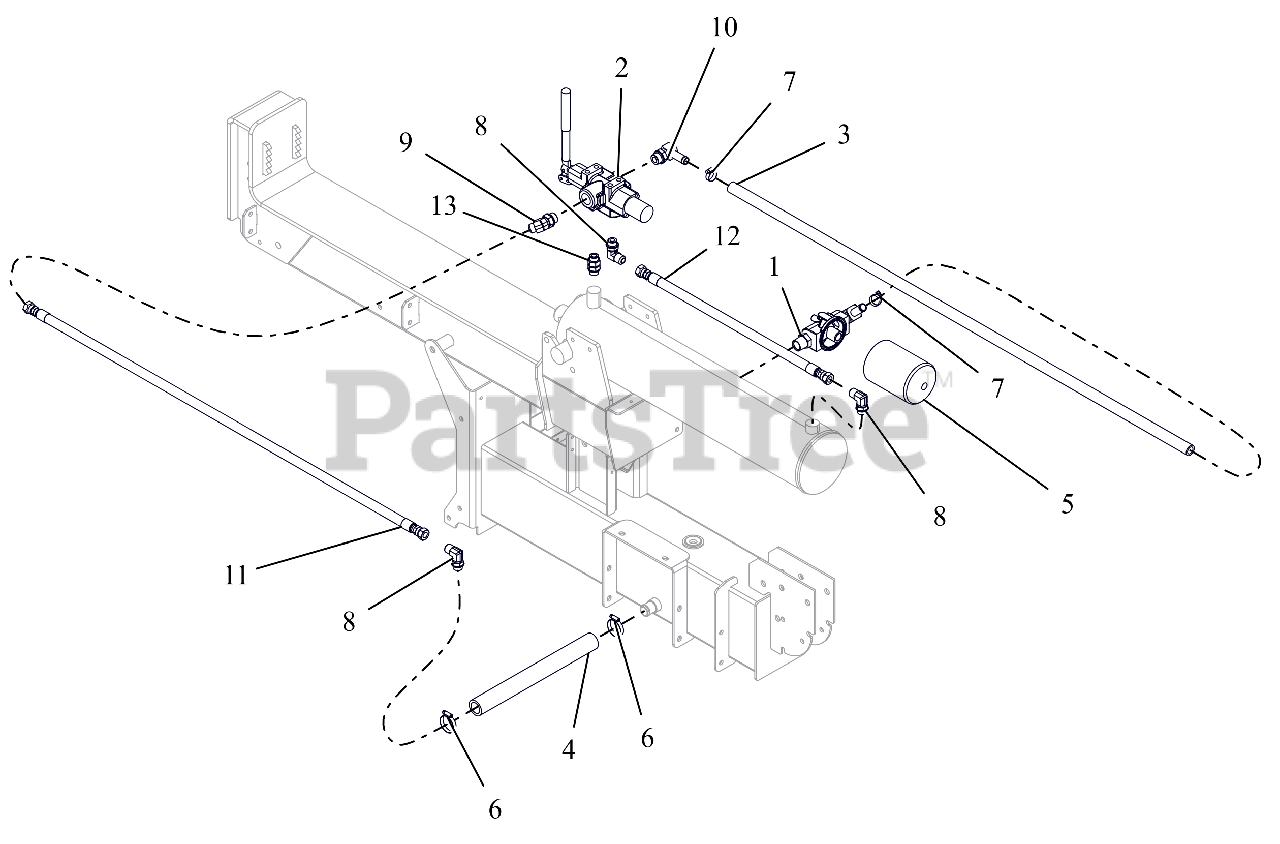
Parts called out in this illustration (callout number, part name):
1	ASM, FILTER HEAD
2	VALVE CONTROL-SPLITTER
3	HOSE,HYD RETURN 10LOLA X 53"
4	HOSE,HYD SUCTION 16G4H X 13.5
5	FILTER,HYDRAULIC OIL-NO BYPASS
6	CLAMP-HOSE 1.50X.81X1.42
7	CLAMP,.88 DIA. HOSE
8	FTG,HYD 6801-8-8
9	FTG,HYD 6802-8-10
10	FTG,HYD 4601-10-10
11	HOSE, ASM - 46"
12	HOSE, HYD - 22"
13	FTG, HYD - STR 08MAORB-08MORB
